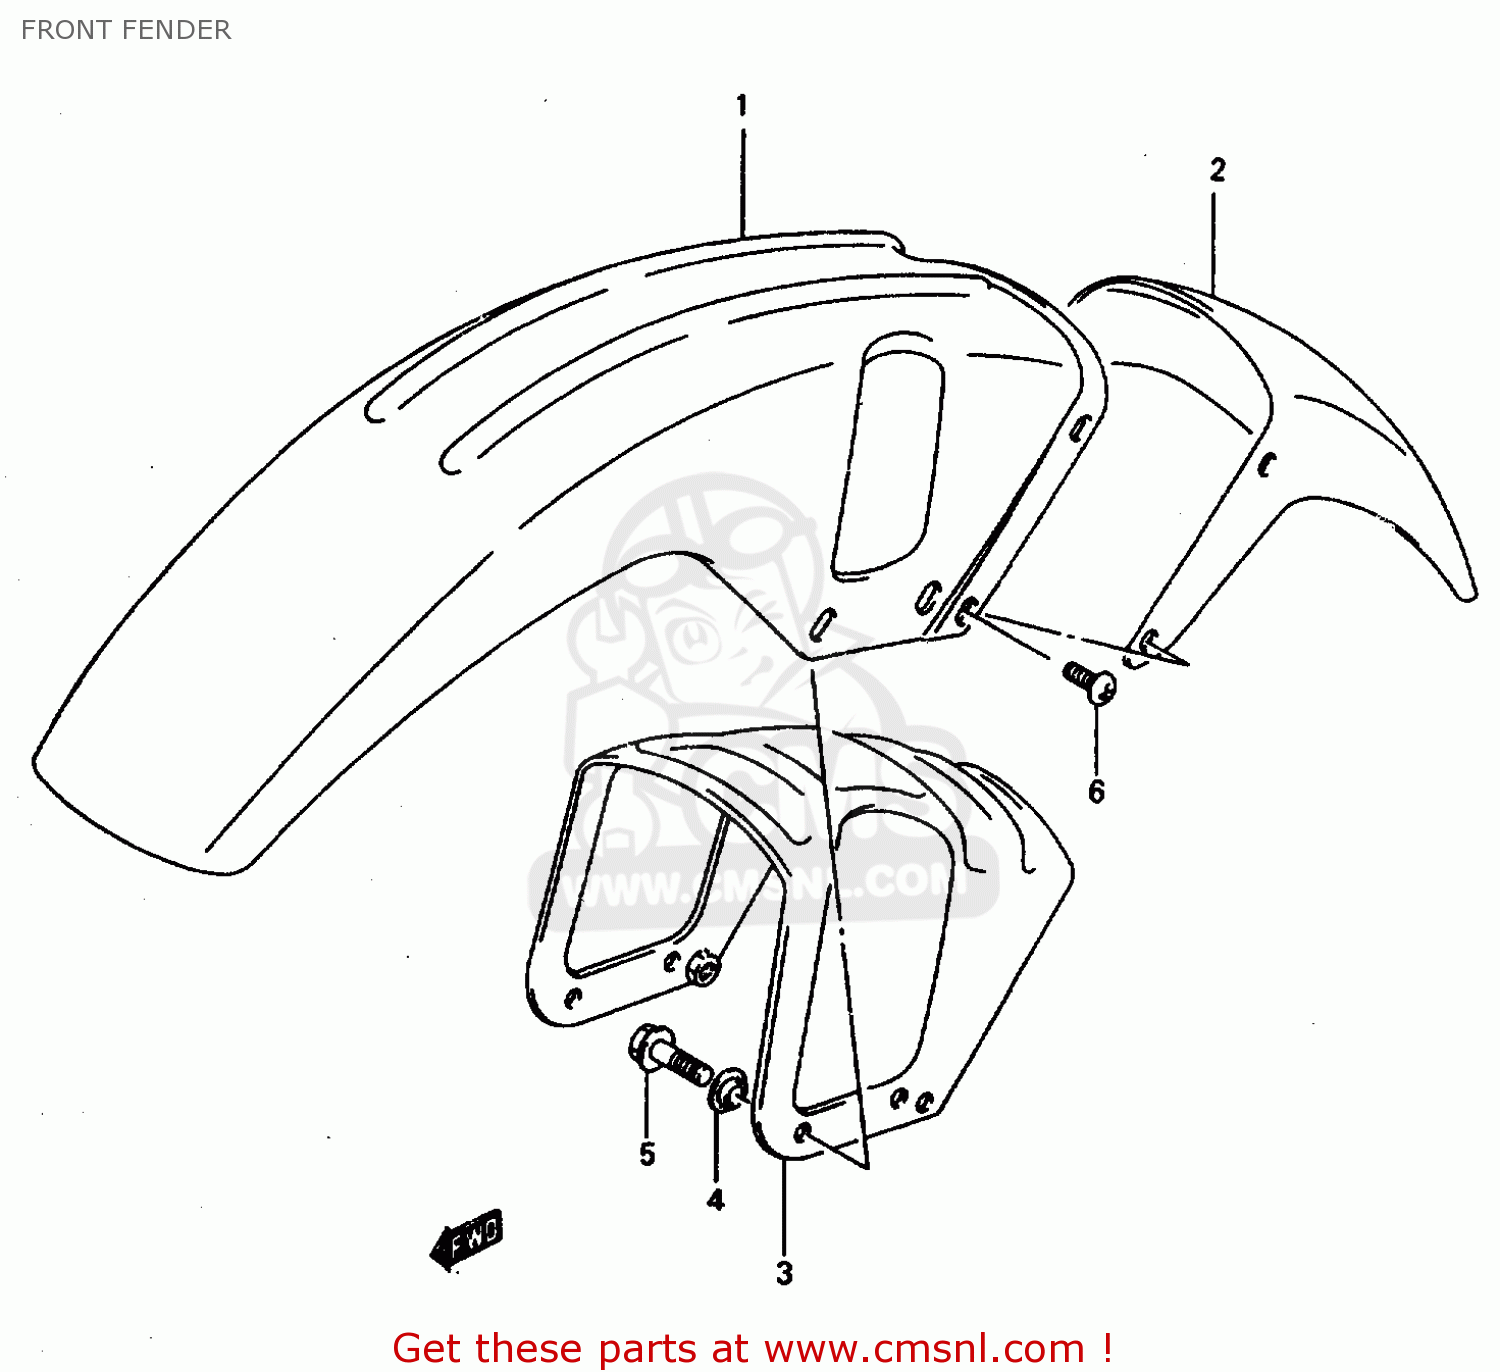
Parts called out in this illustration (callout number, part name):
1	FENDER,FR NO,1
2	FENDER,FR NO,2
3	BRACE, FENDER
4	WASHER
5	BOLT
6	SCREW 5X12
